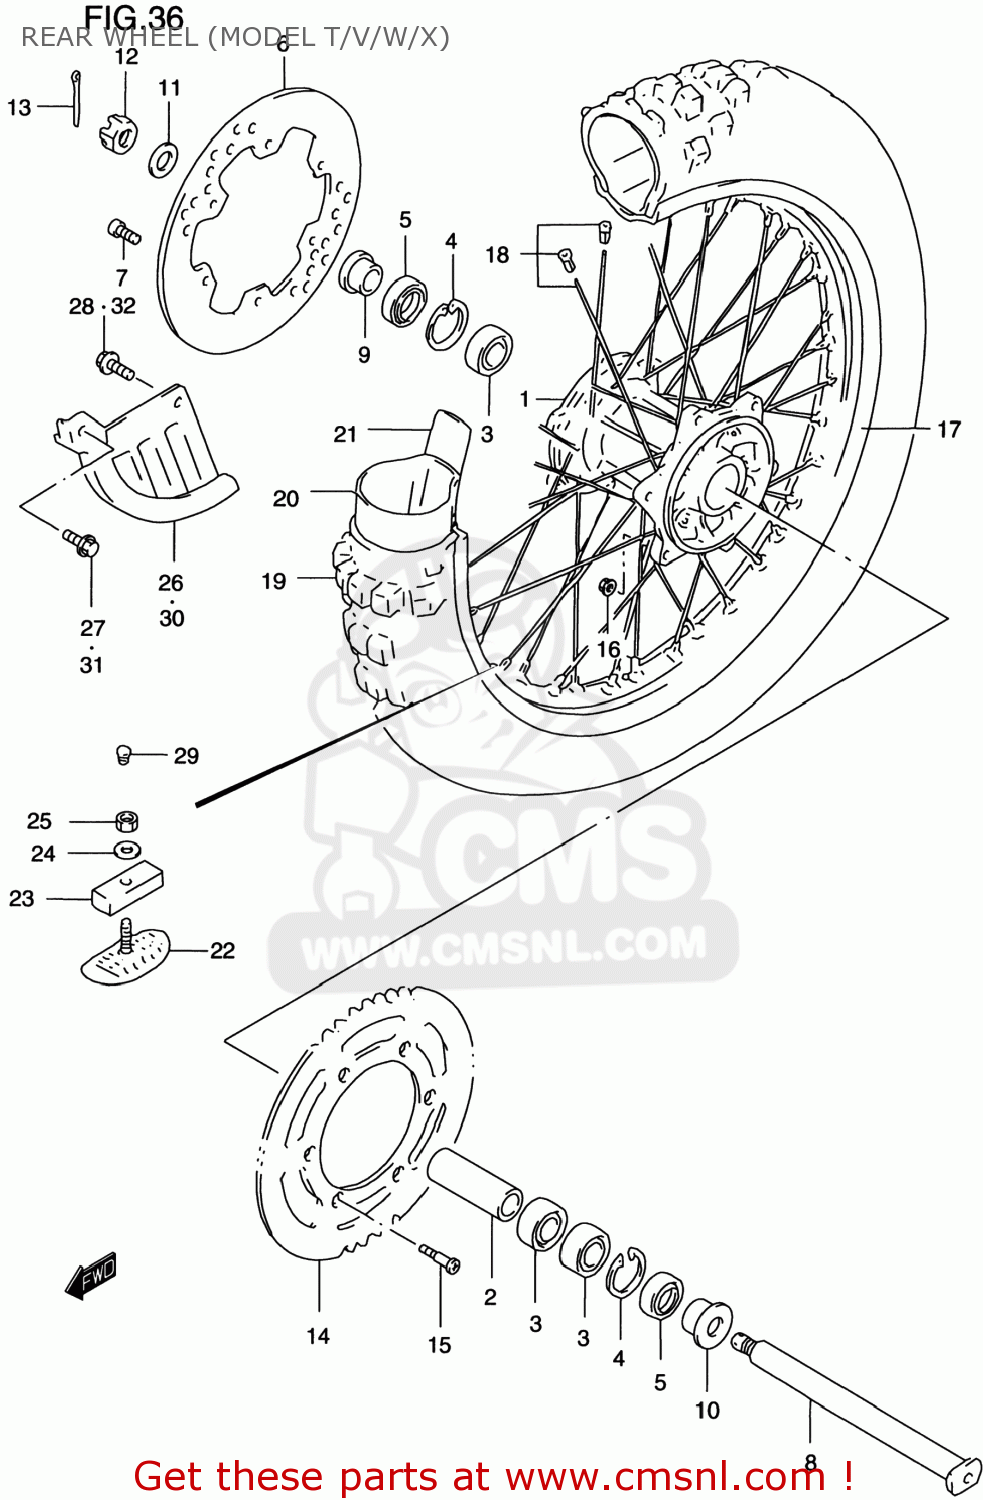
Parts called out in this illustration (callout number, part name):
1	HUB,RR WHEEL
2	SPACER,RR HUB BEARING
3	BEARING
4	CIRCLIP
5	SEAL(29X42X6)
6	DISC,RR BRAKE
7	SCREW
8	AXLE,RR
9	SPACER,RR AXLE
10	SPACER,RR AXLE
11	WASHER(19X32X3.2)
12	NUT
13	PIN,COTTER
14	SPROCKET,RR(NT:48)
15	BOLT(8X30.5)
16	NUT
17	RIM,RR WHEEL(2.15X19 AL)
18	SPOKE SET,RR WHEEL
19	TIRE,REAR 110/90-19
20	TUBE ASSY,WHEEL INNER
21	PROTECTOR,WHL INR TUBE
22	STOPPER,BEAD(2.15)
23	CUSHION,BEAD STOPPER
24	WASHER
25	NUT
26	COVER SET,RR BRAKE DISC
27	BOLT
28	BOLT
29	CAP(OD:12)
30	COVER,REAR DISC
31	BOLT
32	BOLT
